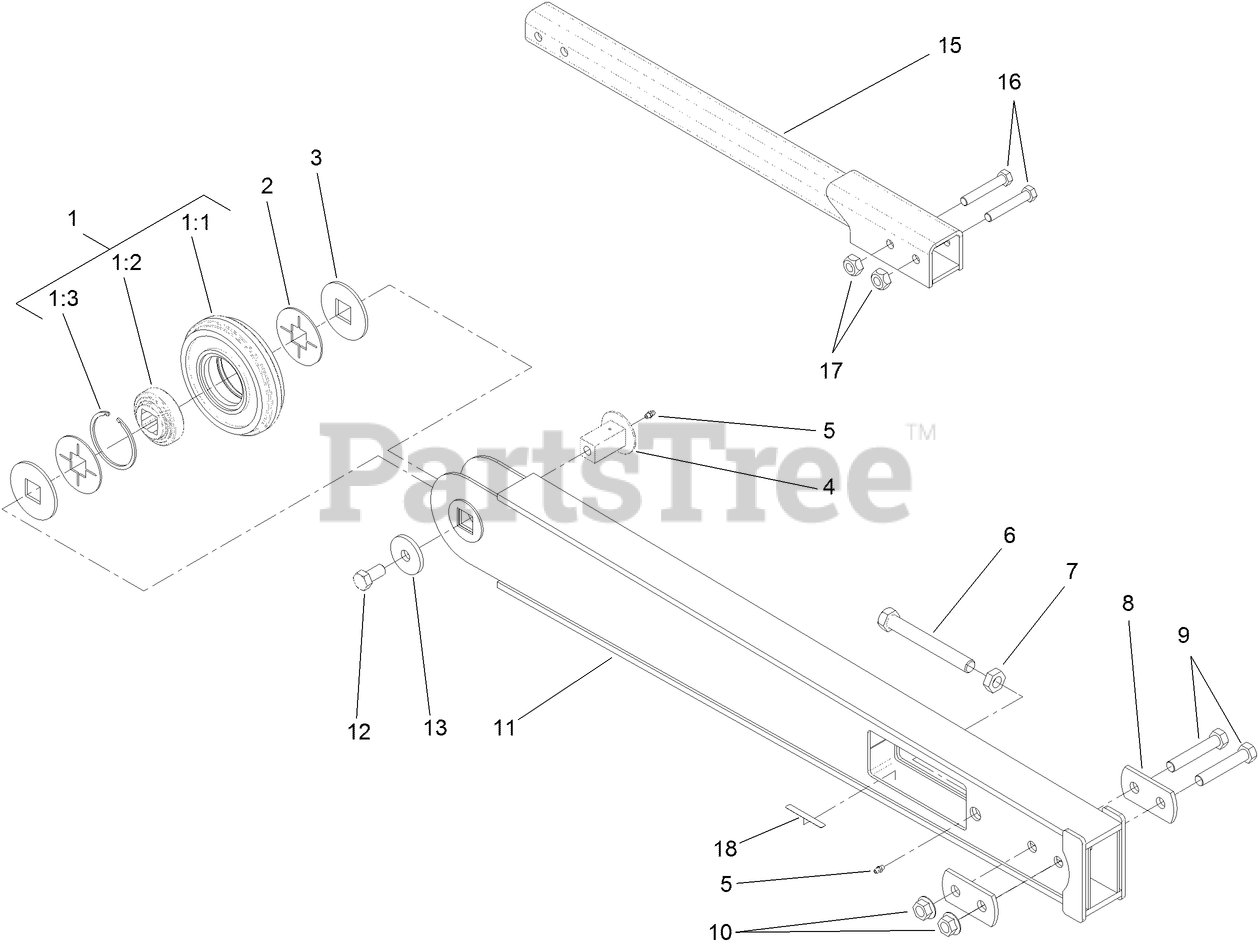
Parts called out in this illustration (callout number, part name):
1	TRENCHER ROLLER ASM
1:1	ROLLER-NOSE
1:2	BEARING
1:3	RING-RETAINING
2	SPACER-ROLLER
3	CAP-ROLLER
4	AXLE-ROLLER
5	FITTING-GREASE
6	BOLT-ADJUSTMENT
7	NUT-JAM
8	PLATE-SUPPORT
9	SCREW-HH
10	NUT-FLANGE
11	48 INCH BOOM ASM
12	SCREW-HH
13	WASHER
15	SAFTEY BAR EXTENSION ASM
16	SCREW-HH
17	NUT-HEX
